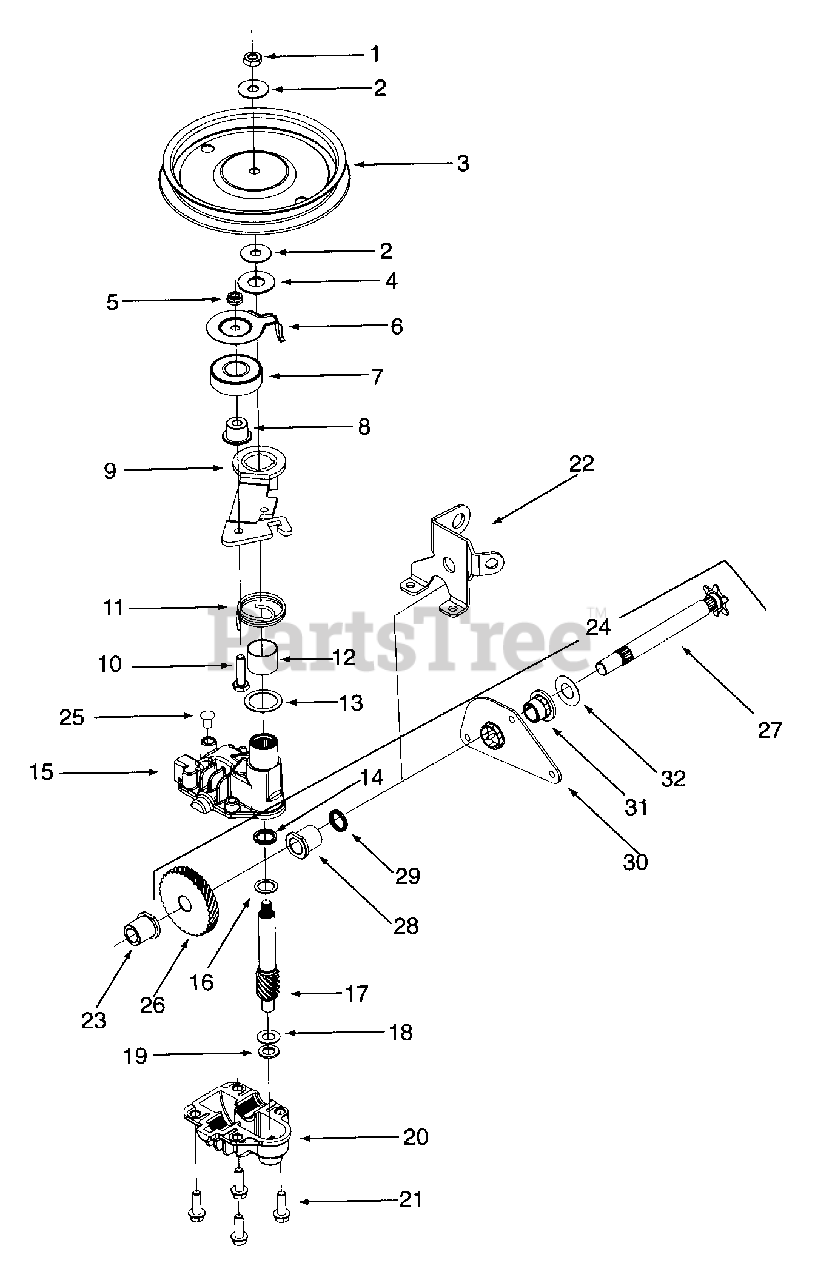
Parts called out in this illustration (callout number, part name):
1	Hx . Jam Nut 5/16-24
2	Bell Wash. .325 x .930 x .045
3	Pulley
4	F Wash. .510 x 1.120 x .060
5	Hx . Jam Nut 1/4-28
6	Belt Keeper
7	Bearing
8	Flange Spacer
9	Idler Bracket Ass'y.
10	Hx . Cap Scr. 1/4-28 x 1.00 Gr. 5
11	Torsion Spring
12	Bearing Sleeve
13	Fl. Wash. .885 x 1.145 x .030
14	Oil Seal
15	Upper Housing Ass'y.
16	Fl. Wash. .504 x .700 x .030
17	Pinion Shaft 10 T.
18	Thr. Wash. 3/8 x .70 x .030
19	Thr. Wash. .388 x .625 x .062
20	Lower Housing Ass'y.
21	Hx . Scr. 1/2-20 x .75
24	Shaft Ass'y.
26	Gear 34 T.
27	Output Shaft 6 T.
28	Flange Bearing
29	Oil Seal
30	Pivot Bracket
31	Flange Bearing
32	Wash. Fl. .508 I.D. x 1.00 O.D. x .020.020
